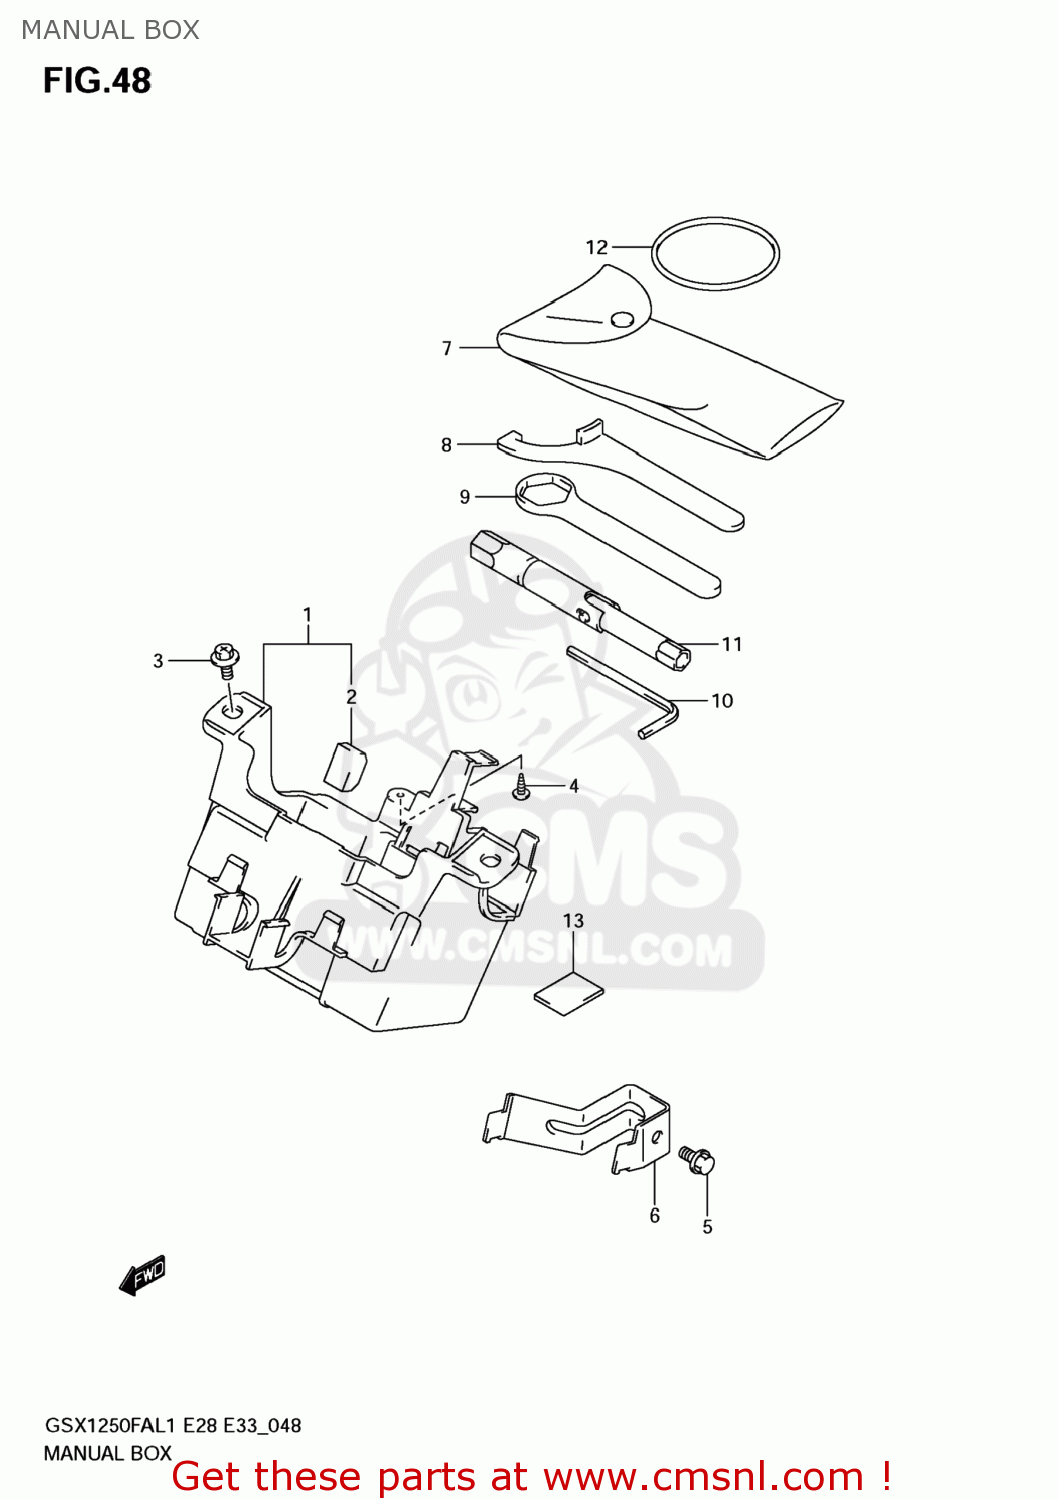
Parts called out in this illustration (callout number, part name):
1	HOLDER,BATTERY
2	CUSHION,BATTERY HOLDER
3	BOLT(6X12)
4	SCREW(5X16)
5	BOLT
6	PLATE,FUSE BOX
7	TOOL ASSY
8	CLAMP
9	RING SPANNER(36)
10	HEXAGON SPANNER,5
11	SPARK PLUG WRENCH
12	O RING(D:3.5,ID:61)
13	CUSHION(30X50X3)
